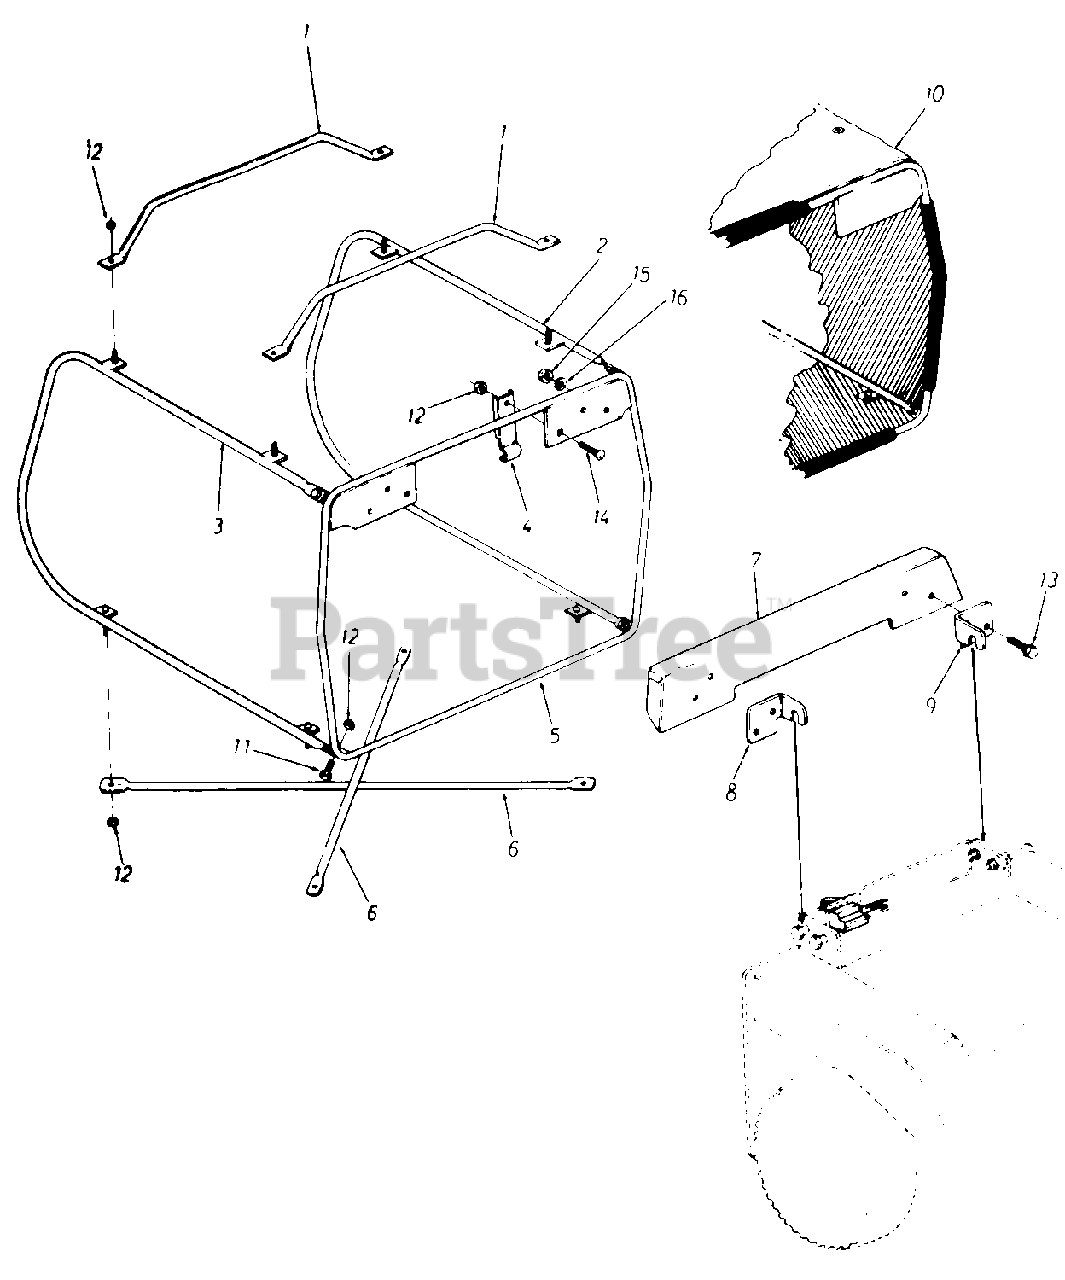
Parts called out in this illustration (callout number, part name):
1	Catcher Handles
2	Catcher Side Frame Ass'y. L.H.
3	Catcher Side Frame Ass'y. R.H.
4	Switch Actuator Bracket
5	Catcher Frame Ass'y.
6	Bottom Cross Brace
7	Dust Cover
8	Hinge- R.H.
9	Hinge- L.H.
10	Grass Bag
11	Hex Scr. 1/4-20 x .62" Lg.*
12	Hex Cent. L-Nut 1/4-2 Thd.
13	Hex Sems Scr. 5/16-18 x 1.00" Lg.*
14	Carriage Bolt 1/4-20 x .62" Lg.*
15	Hex Nut 5/16-18 Thd.*
16	L-Wash. 5/16" Scr.*
